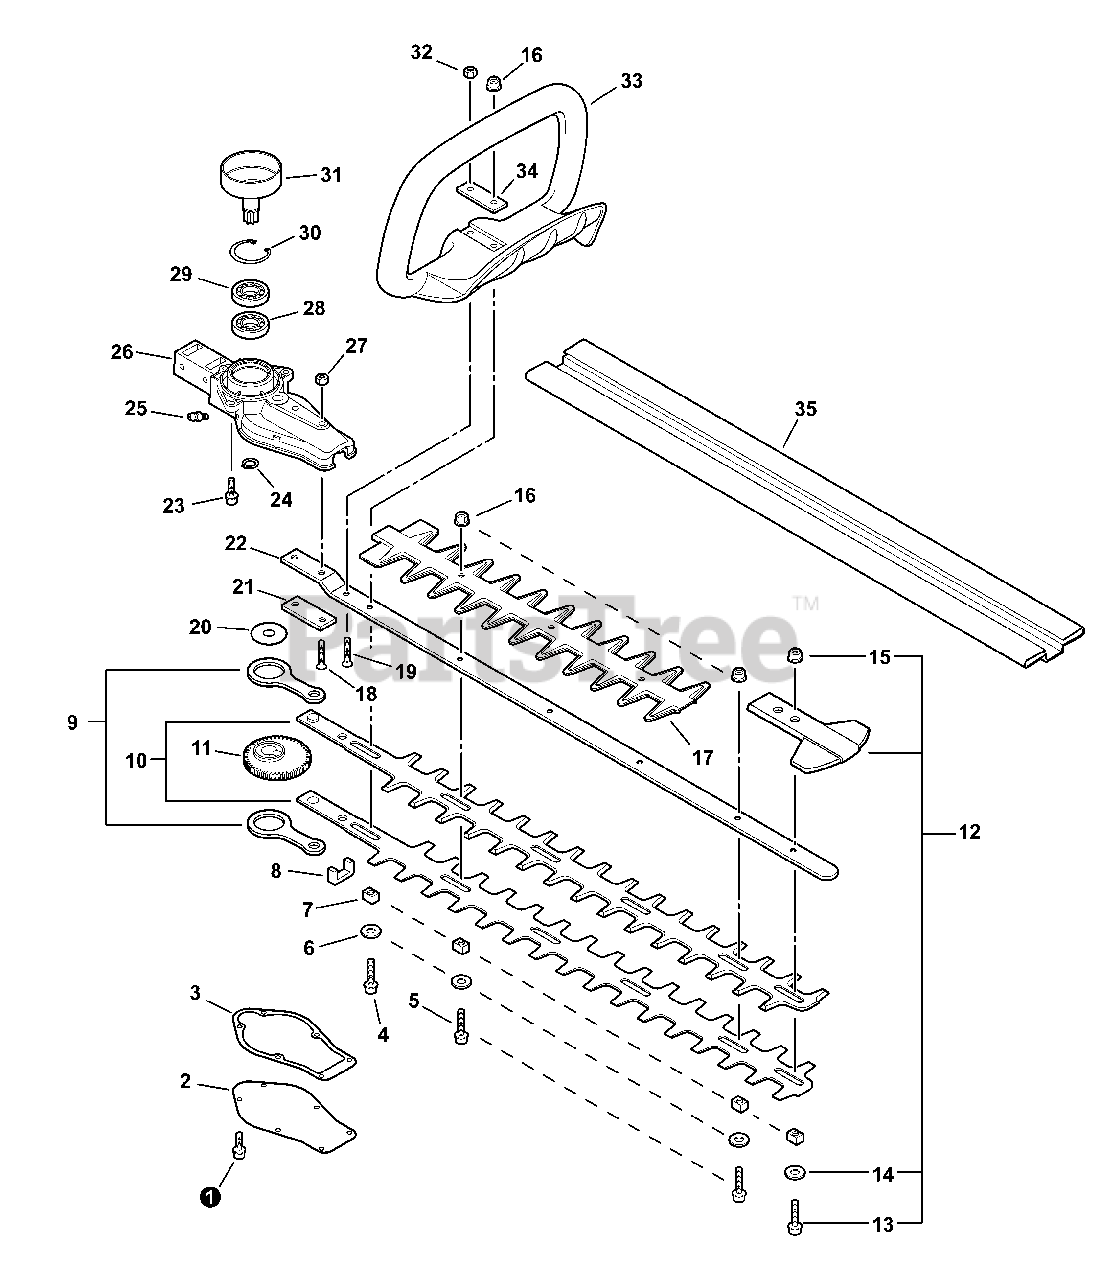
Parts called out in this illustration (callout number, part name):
1	BOLT 4×10
2	COVER, GEAR CASE
3	GASKET, GEAR CASE
4	BOLT 5×40
5	BOLT 5×20
6	WASHER 5
7	GUIDE, BLADE 5
9	ROD, CONNECTING
10	CUTTER 20"
12	TIP GUARD KIT
13	BOLT 5×20
14	WASHER 5
15	NUT, FLANGE M5
16	NUT, FLANGE M5
17	GUARD, CUTTER BLADE
18	SCREW 6×25
19	SCREW 5×30
21	PLATE, EYE
22	SUPPORT, BLADE 20"
23	BOLT 5×20
24	RING, SNAP 14
25	FITTING, GREASE
26	GEAR CASE ASSY
27	NUT, HEX M6
28	BEARING, BALL 6202
29	BEARING, BALL 6202
30	RING, SNAP 35
31	DRUM, CLUTCH
32	NUT, LOCK M5
33	HANDLE, FRONT
34	PLATE, EYE
35	SCABBARD 23.6"
